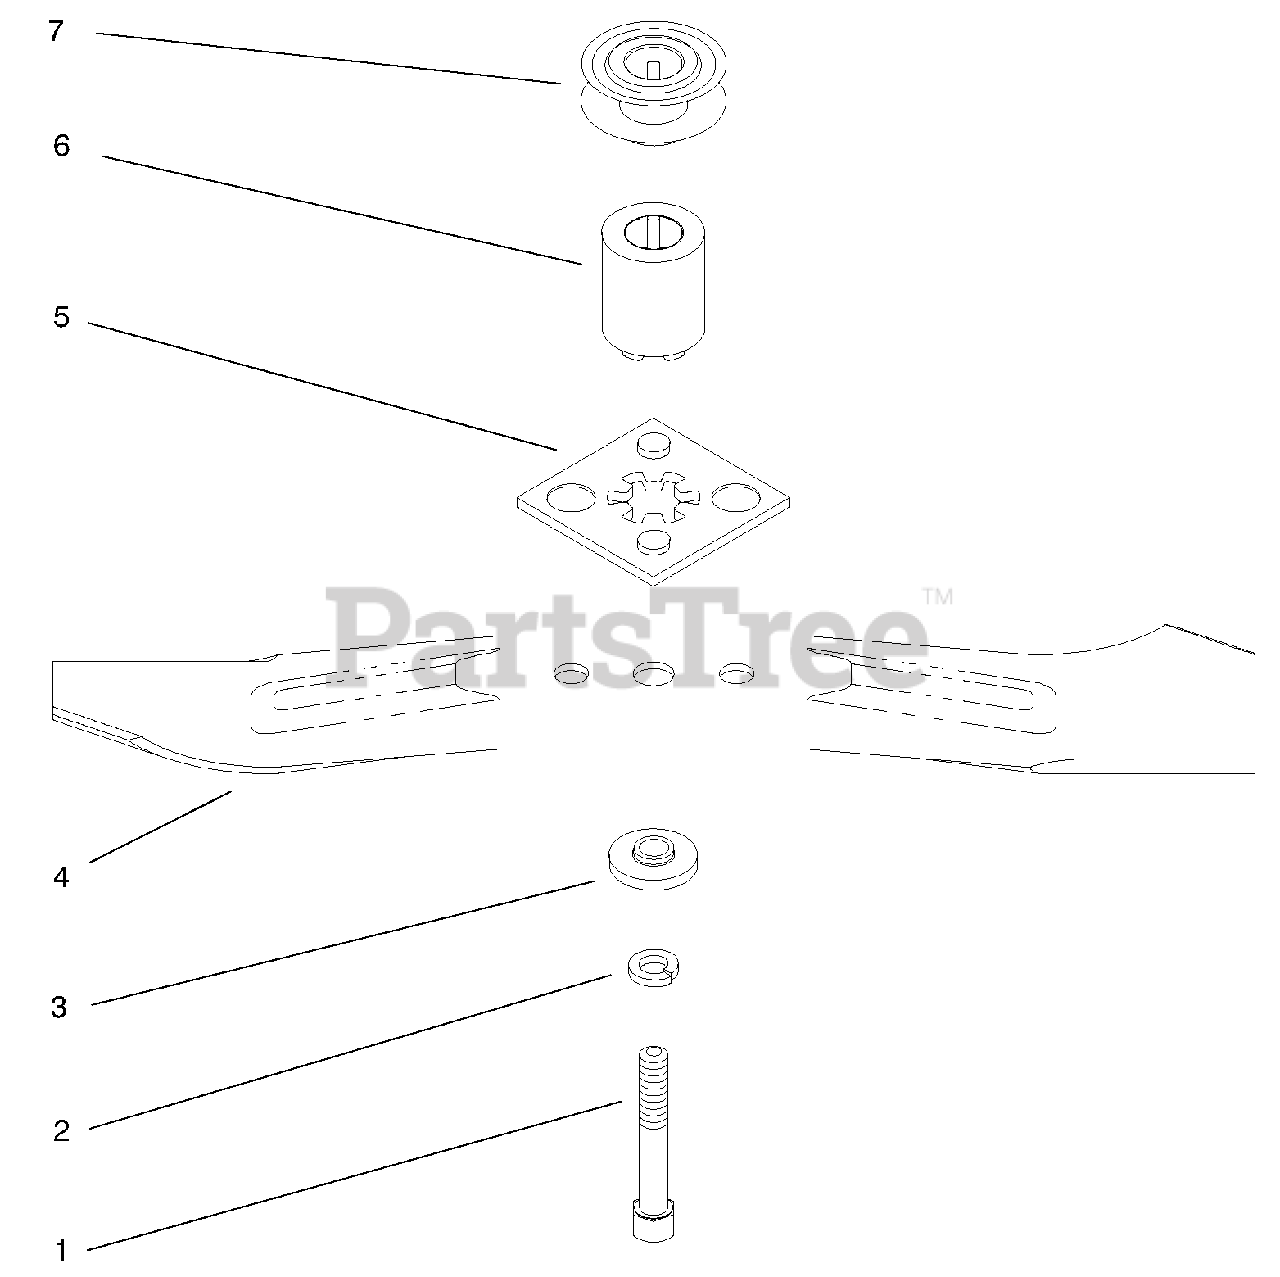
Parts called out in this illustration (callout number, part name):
1	Bolt-Blade
2	Washer-Lock
3	Spacer-Blade
4	Blade 19"
5	Plate-Blade Driver
6	Hub-Blade Driver
7	Pulley-Driver
